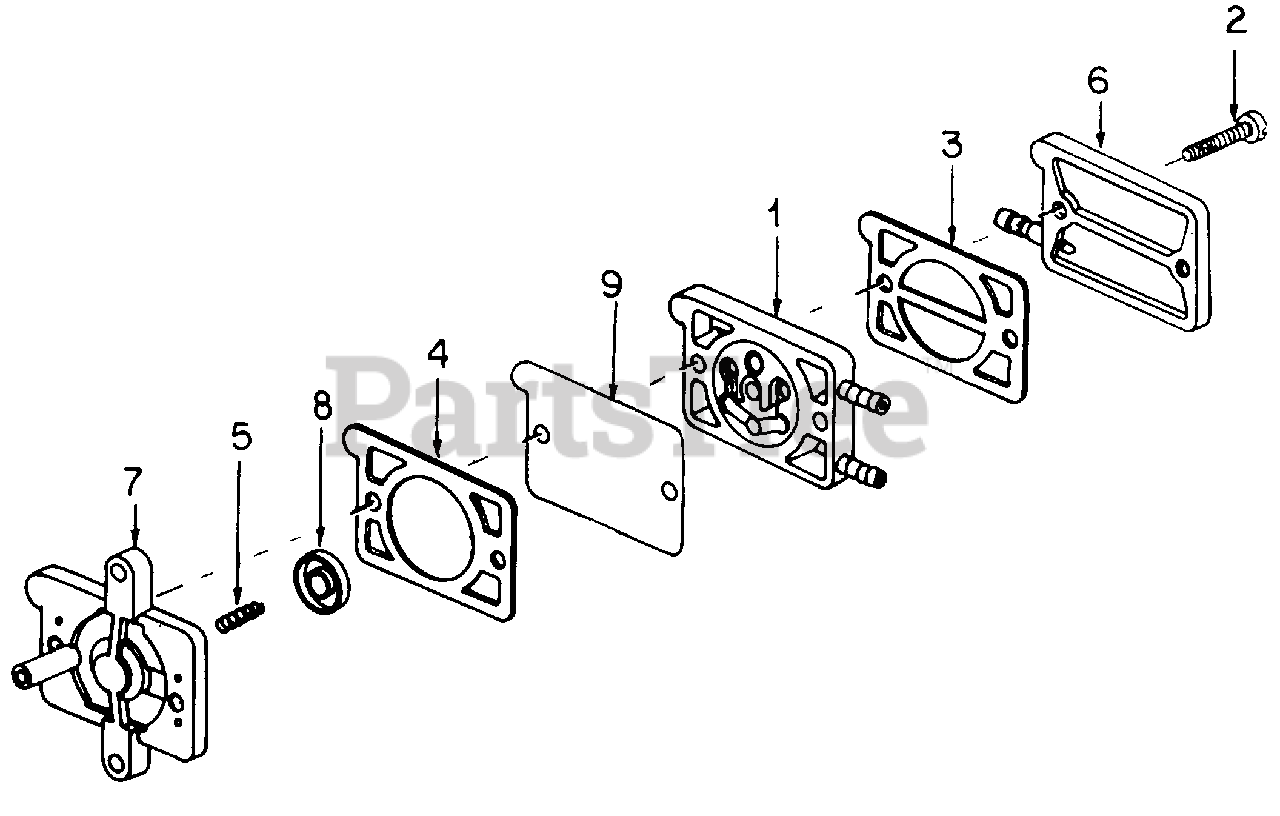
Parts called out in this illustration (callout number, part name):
1	Valve Assy, Reed
2	Screw, Pump Cover to Body
3	Gasket, Cover to Valve
4	Gasket, Pump Cover
5	Spring, Fuel Pump
6	Cover, Pump
8	Plate, Drive
